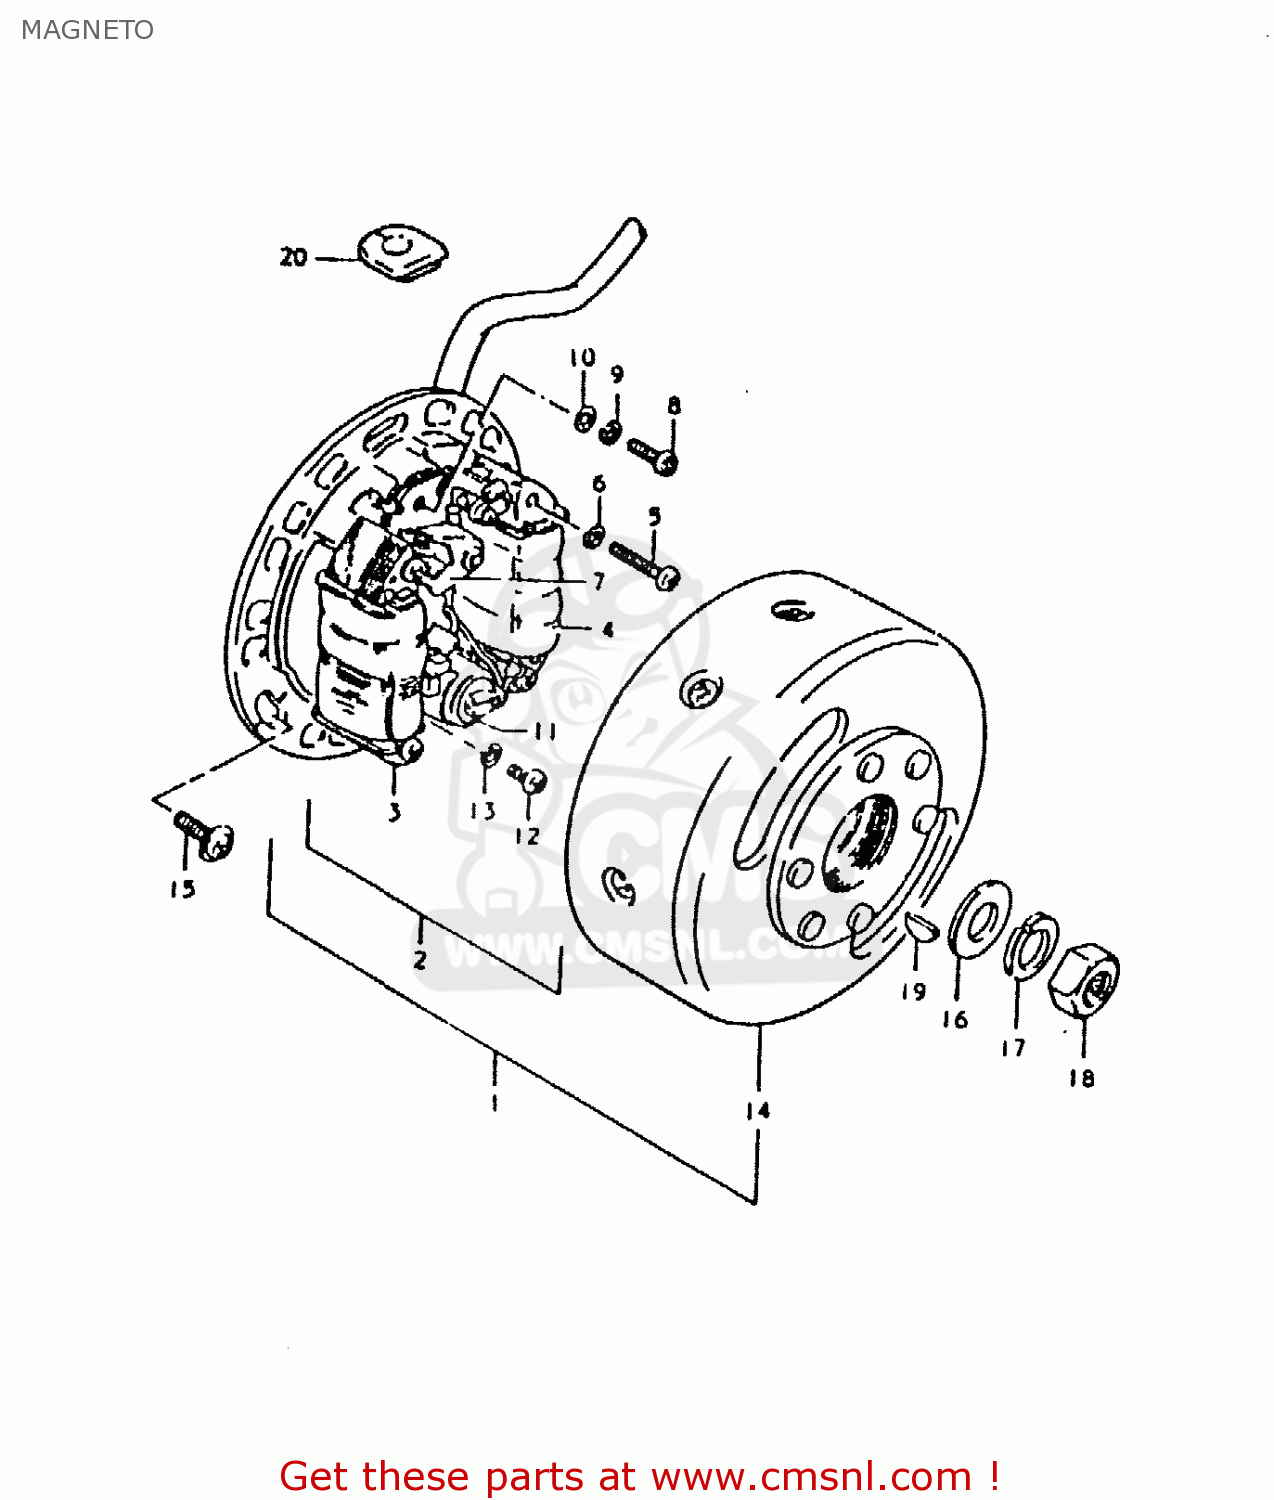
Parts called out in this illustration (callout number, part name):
1	MAGNETO ASSY
2	STARTER ASSY
3	COIL,LIGHTING
4	COIL,PRIMARY
5	SCREW
6	LOCK WASHER
7	POINT ASSY,CONTACT
8	SCREW(4X10)
9	LOCK WASHER
10	WASHER
11	CONDENSER
12	SCREW
13	LOCK WASHER
14	ROTOR
15	SCREW(5X14)
16	WASHER
17	LOCK WASHER
18	NUT (10MM)
19	KEY
20	GROMMET
